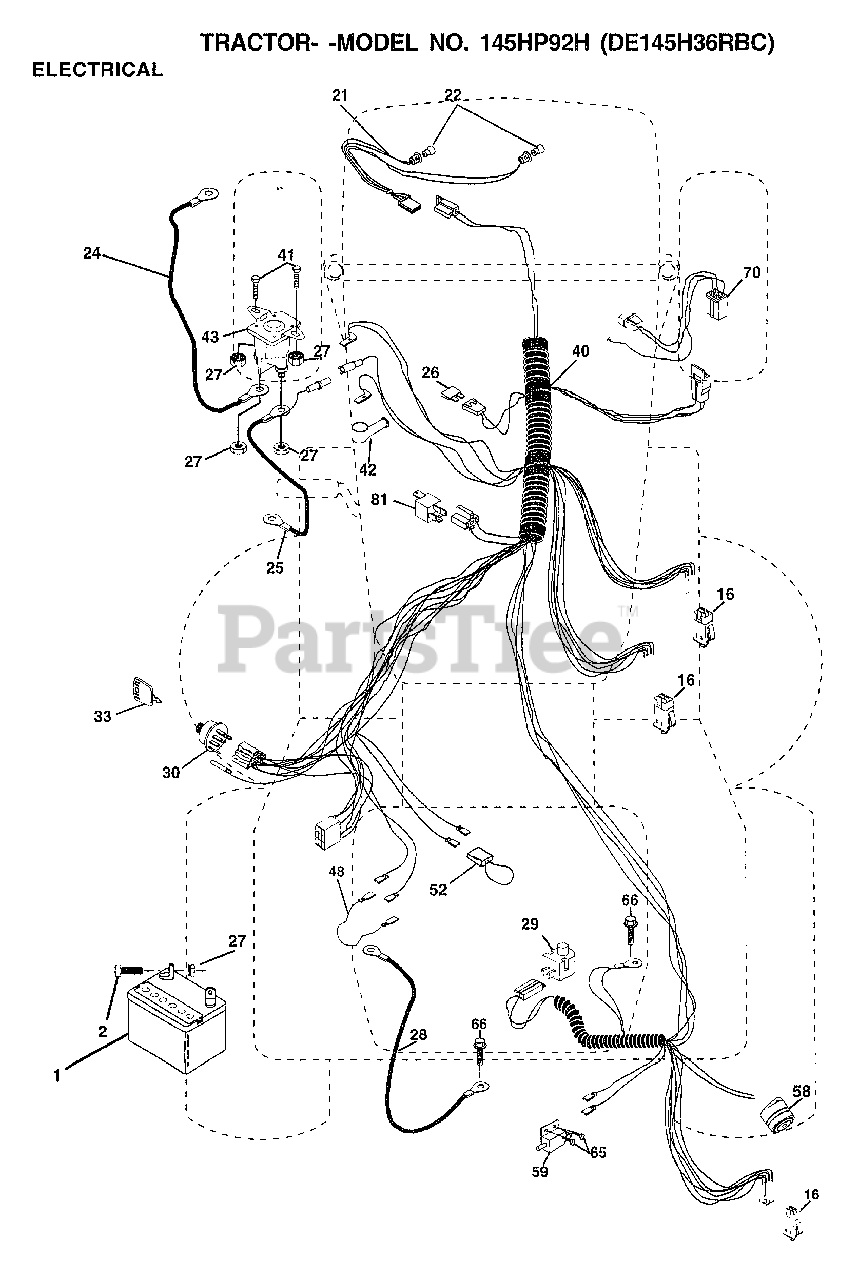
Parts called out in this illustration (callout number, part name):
2	BOLT LT
16	SWITCH INTERLOCK
21	HARNESS.ASM.LIGHT W/4152J
22	HEADLAMP BULB
24	"CABLE T, BATTERY"
25	CABLE.BATTERY.CRD
26	FUSE.15 AMP
27	NUT
28	"CABLE.GRD.6GA/18""BLACK"
29	SWITCH.PLUNGER
30	SWITCH.IGN.
33	KEY MLD GEN DELTA
40	HARNESS IGN CORD
41	BOLT HXHD FIN
48	ADAPTER AMMETER
52	PROTECTION LOOP
58	BUZZER CRD
59	SWITCH.FBI.CRD
65	SCREW
66	SCREW LT
70	HARNESS
81	RELAY ASSY T
